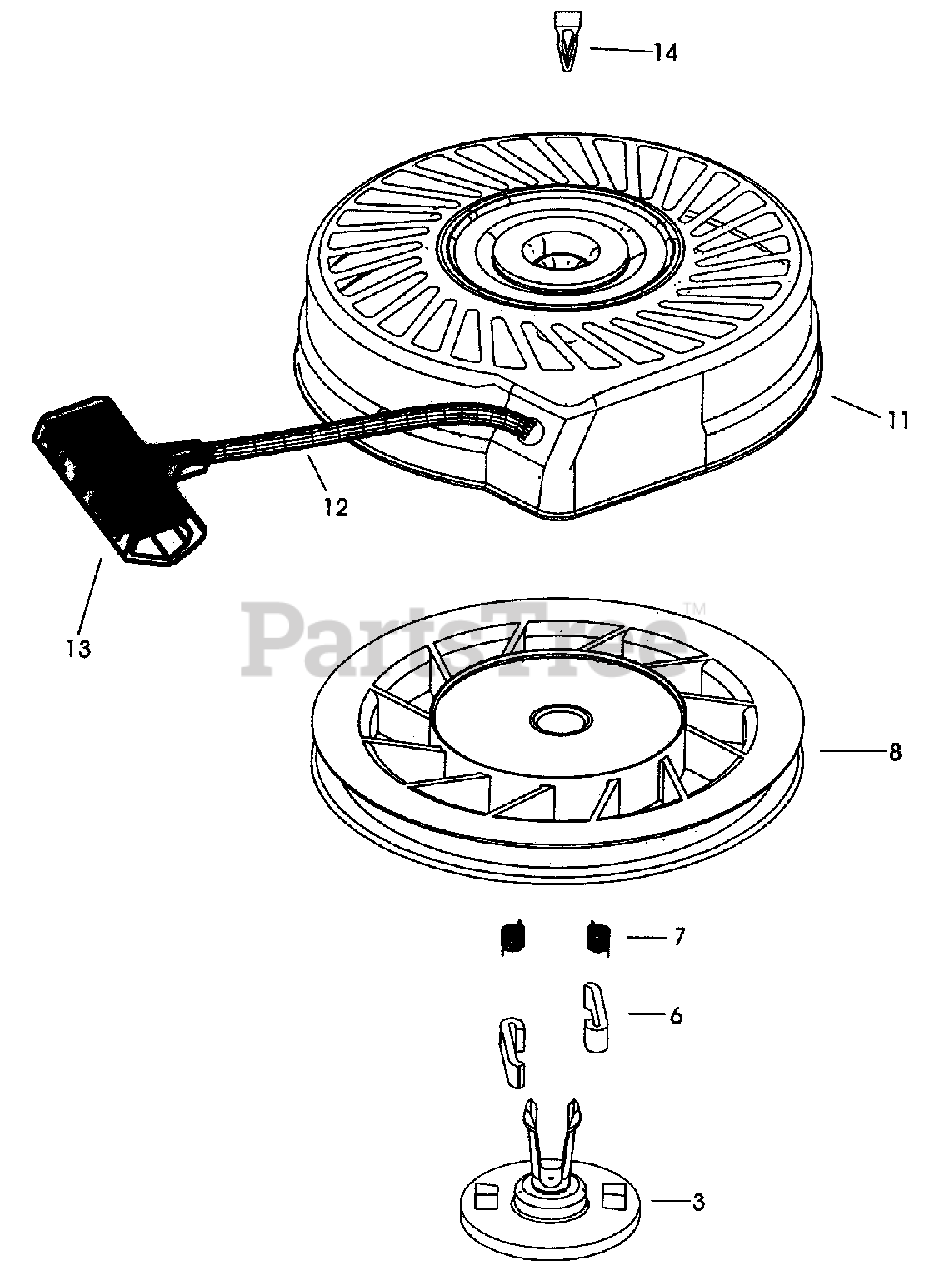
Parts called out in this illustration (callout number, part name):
3	Retainer
6	Starter Dog
7	Dog Spring
8	Pulley & Rewind Spring Ass'y
11	Starter Housing Ass'y (40 degree grommet)
12	Starter Rope (Length 98" x 9/64" dia.)
13	Starter Handle
14	Locking Tab
